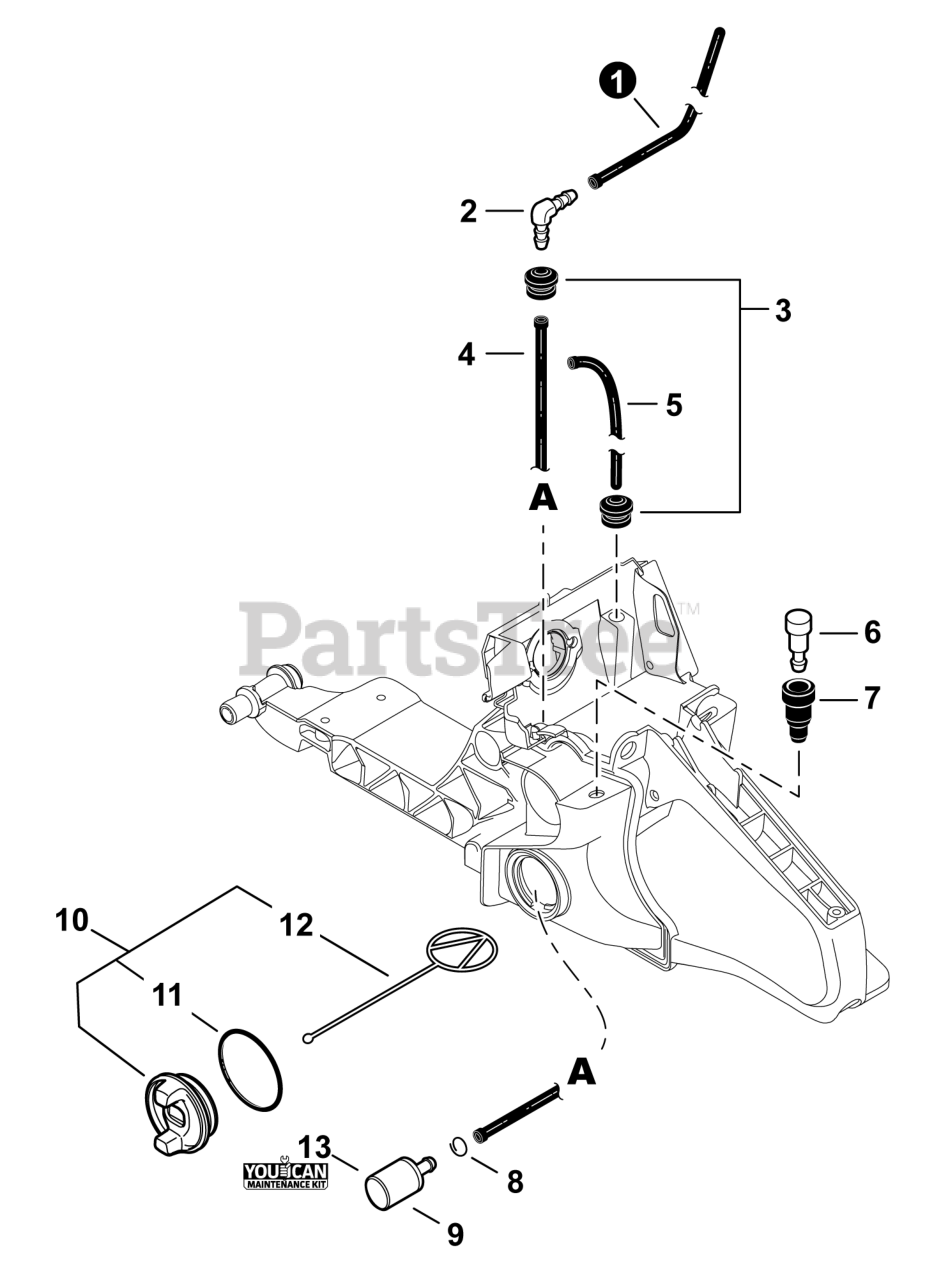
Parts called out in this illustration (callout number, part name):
1	PIPE, FUEL 3×6×135
2	CONNECTOR, PIPE
4	PIPE, FUEL 3×5×120 BLACK
5	PIPE, IMPULSE 3×6(8)×160
6	VENT ASSY
7	GROMMET, VENT
8	CLIP Ø6
9	FILTER, FUEL
10	CAP ASSY, FUEL
11	O-RING 29
12	FUEL CAP CONNECTOR (L=60MM)
13	TUNE-UP KIT - YOUCANT
